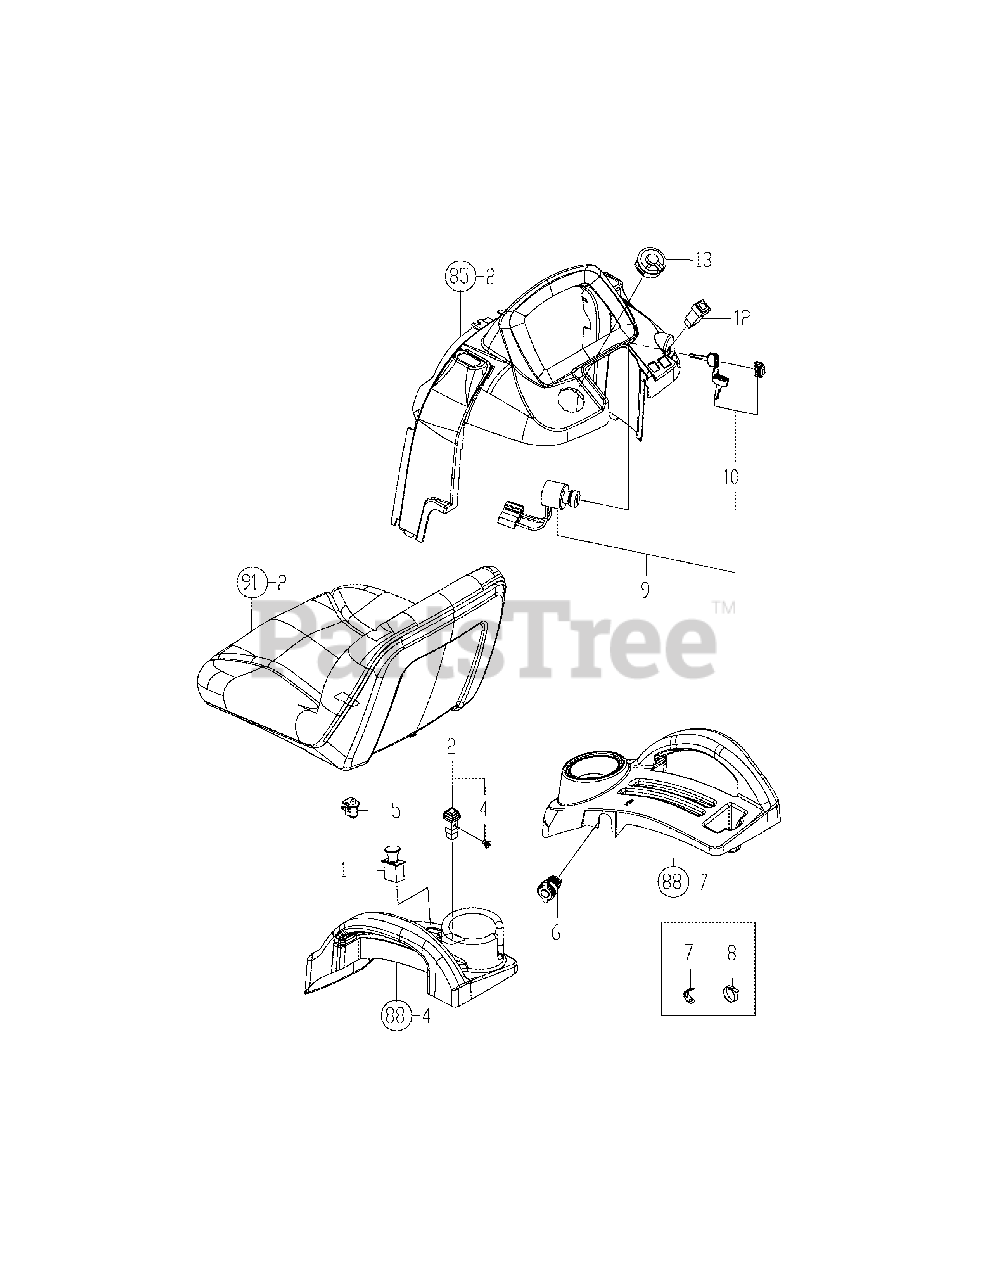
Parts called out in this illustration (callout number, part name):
5	Switch, Seat,Delta,As
6	Dc Power Outlet
7	Clamp, Wiring
9	Switch Assy, Starter
13	Switch, Combination
